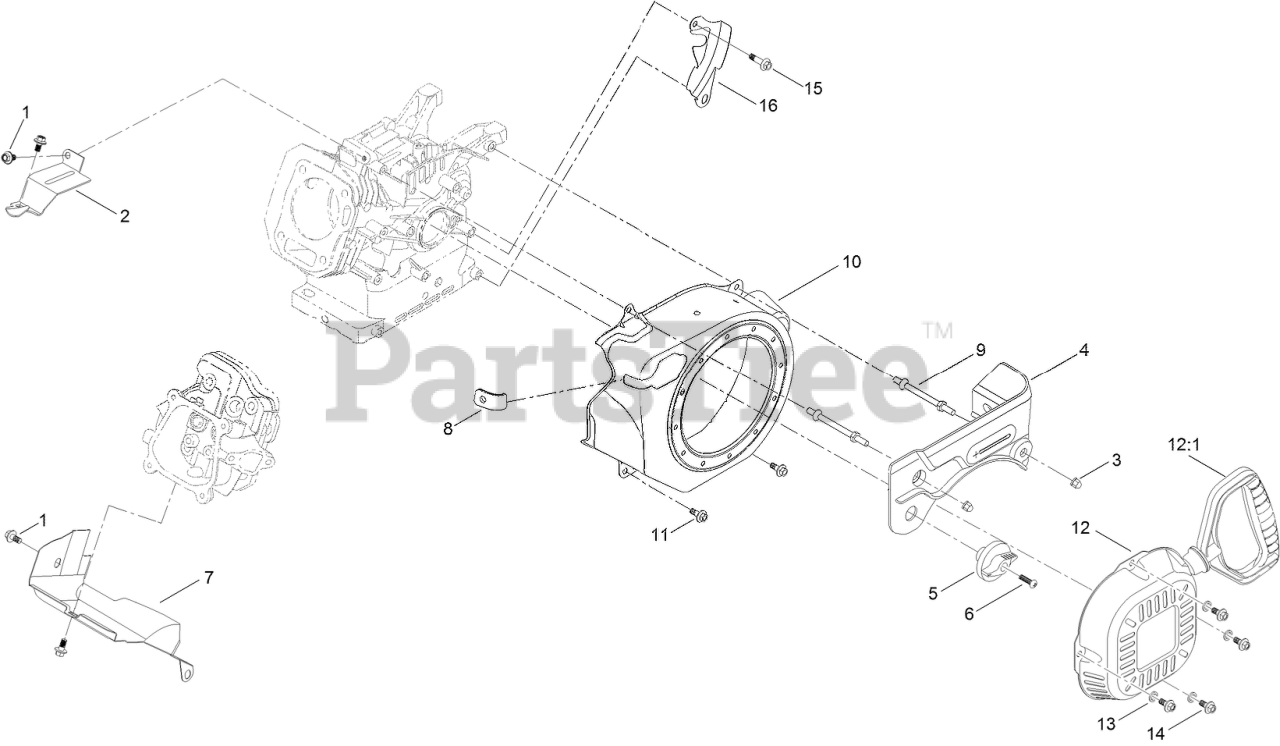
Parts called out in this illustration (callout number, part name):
1	SCREW-HHF
2	BAFFLE
3	NUT-ACORN
4	PANEL-CONTROL
5	KNOB-VALVE, FUEL
6	SCREW-BHP
7	SHROUD-LOWER
8	BLOCK-RUBBER
9	STUD-MOUNT
10	SHROUD-BLOWER
11	SCREW-HHF
12	RECOIL STARTER ASM
12:1	HANDLE-RECOIL
13	WASHER-PLAIN
14	SCREW-HHF
15	SCREW-HHF
16	SHIELD-FLYWHEEL
